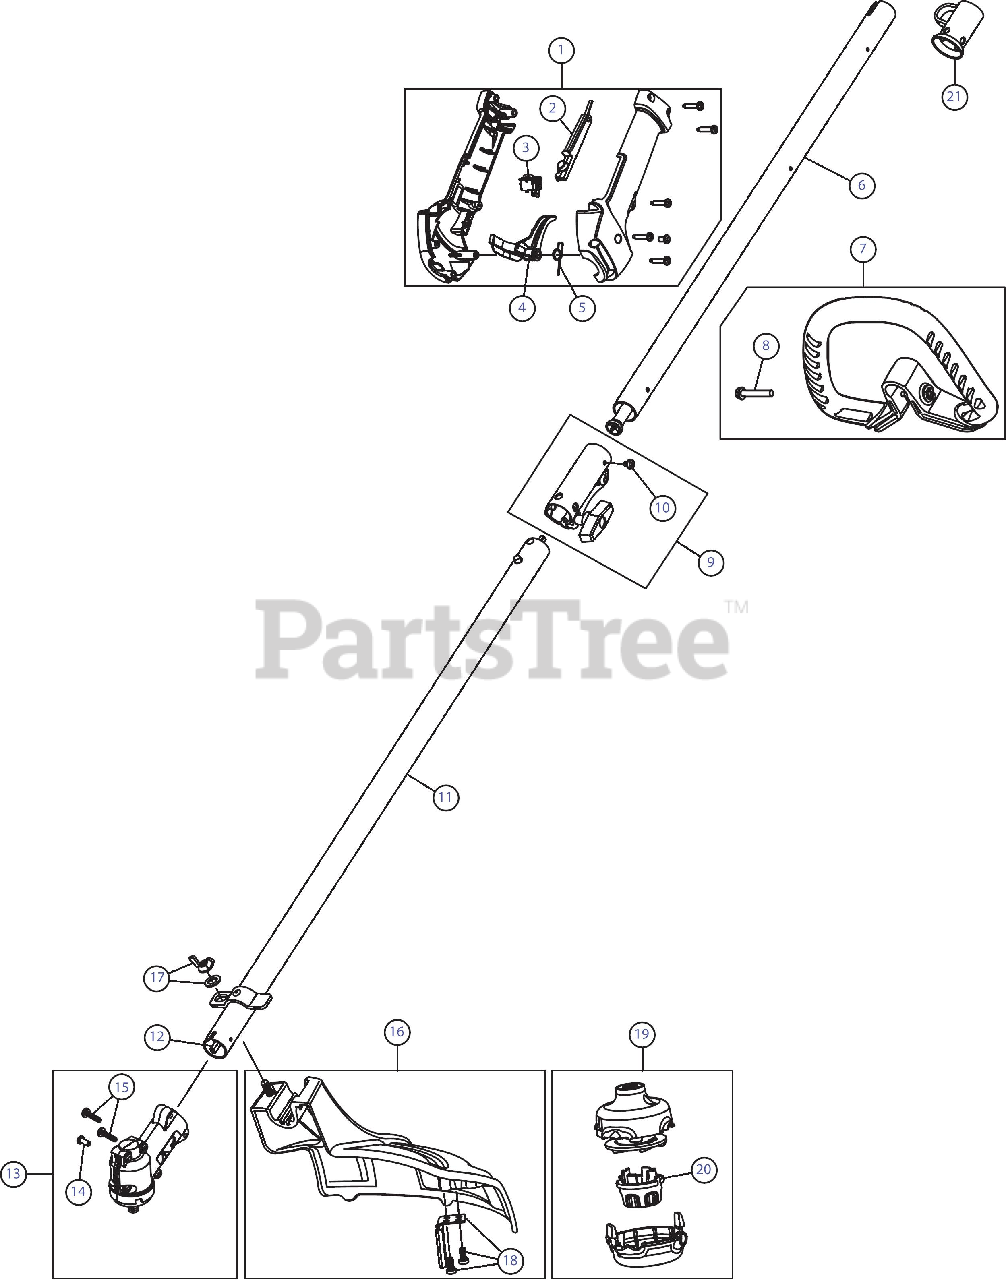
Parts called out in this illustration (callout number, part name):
1	Throttle Housing Assembly (includes 2 - 5)
2	Throttle Trigger Lock-Out
3	Trigger Switch Assembly
4	Throttle Trigger Spring
5	Throttle Trigger
6	Upper Shaft Housing Assembly
7	D-Handle (includes 8)
8	D-Handle Hardware
9	Split Boom Coupler (includes 10)
10	Anti-Rotation Screw
11	Lower Shaft Housing Assembly (includes 12)
12	Lower Flexible Drive Shaft
13	Gearbox Assembly (includes 14 & 15)
14	Gearbox Anti-Rotation Screw
15	Gearbox Mounting Hardware
16	Shield Assembly (includes 17 & 18)
17	Shield Mounting Hardware
18	Blade Assembly
19	Cutting Head Assembly (includes 20)
20	Bump Knob
21	Hanger
